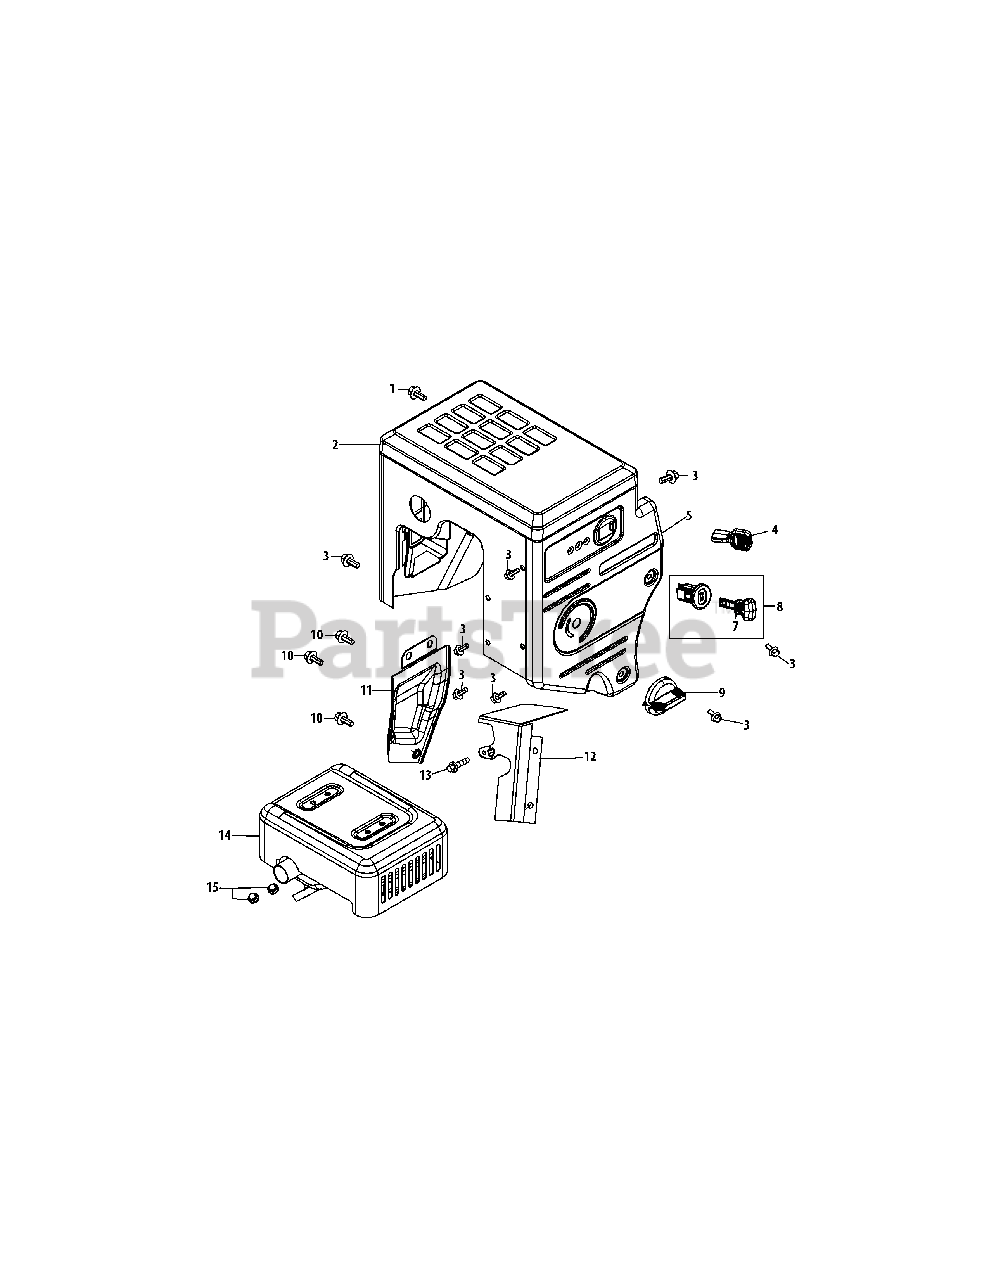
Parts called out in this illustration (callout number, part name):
1	Bolt, M6 x 16
2	Muffler Shield
3	Bolt, M6 x 12
4	Throttle Control Knob
5	Control Panel
7	Key
8	Key Switch Ass’y
9	Choke Knob
10	Bolt, Flange, M6 x 10
11	Muffler Baffle
12	Carb Isolator Bracket
14	Muffler Ass’y
15	Nut, M8 - 1.25
